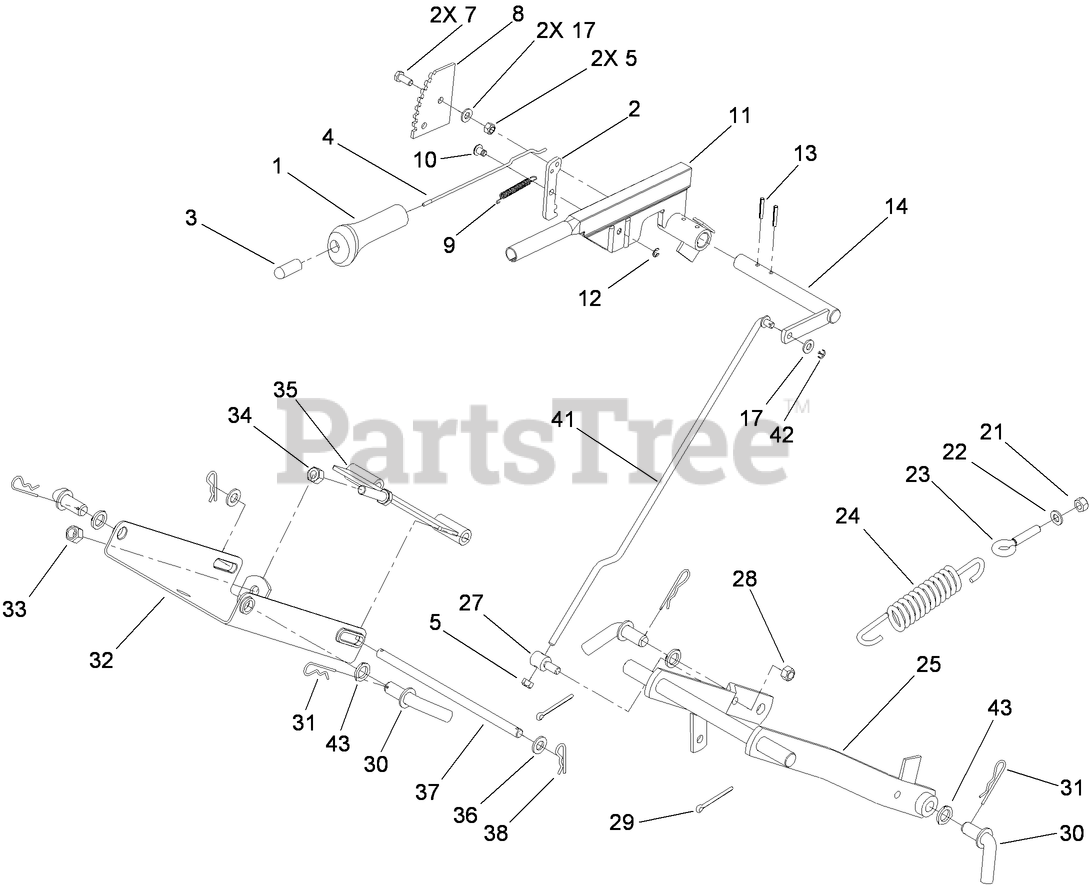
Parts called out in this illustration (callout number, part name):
1	GRIP-HANDLE
2	RATCHET-PLATE, PIVOT
3	BUTTON-PLUNGER
4	ROD-CONNECTION
5	NUT-LOCK, NI
7	SCREW-HH
8	GEAR-SEGMENT, DECK LIFT
9	SPRING
10	PIN-LEVER, ARM
11	LEVER-ARM, HEIGHT ADJ.
12	CLIP-PIN
13	PIN-SPRING
14	SHAFT-LIFT, DECK
17	WASHER-PLAIN
21	NUT-LOCK, NI
22	WASHER-FLAT
23	BOLT-EYE
24	SPRING-LIFT
25	PIVOT ARM ASM
27	PIN-LIFTING
28	NUT-LOCK, NI
29	PIN-COTTER
30	PIN-BENT
31	PIN-HAIR
32	SUSPENSION-MOWER DECK, FRONT
33	NUT-HEX
34	NUT-HEX
35	HOLDER-FRONT
36	WASHER-FLAT
38	PIN-HAIR
41	ROD-HEIGHT, ADJ.
42	PIN-COTTER
43	Washer-Hose
